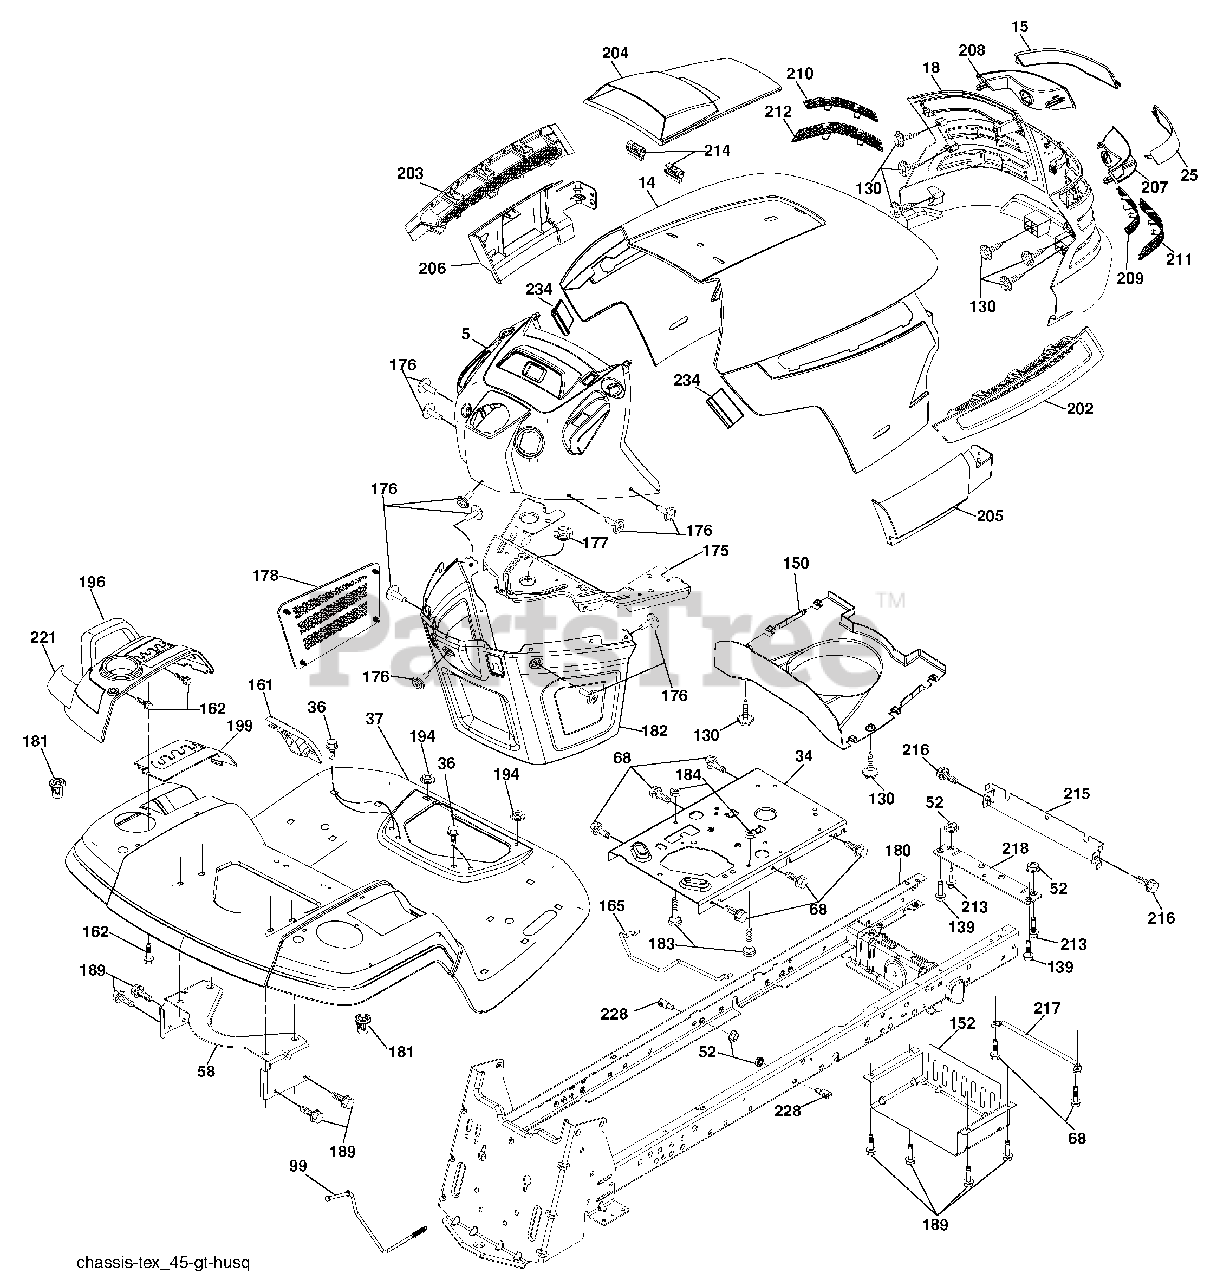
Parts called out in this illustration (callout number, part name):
5	Dash
14	Hood
18	Grille
34	Plate Engine
36	Screw 5/16-18 x 3/4
37	Fender
52	Nut Crown Lock 5/16-18
58	Bracket Fender
68	Screw 5/16-18 x 1/2
99	Rod Bypass Asm.
130	Screw 10 x 3/4 Single Lead Hex
150	Duct Heat Hood
152	Shield Browning/Debris
161	Console Fuel Window
162	Screw Hex Wsh Hi-Lo 1/4 x 1/2
165	Bracket Support Tank
175	Crossmember
176	Screw 10-24 x 5/8 Wshd Qdrx
177	Bushing Steering
178	Cargo Asm. Net
179	Plug N/Cruise
180	Chassis
181	Bushing Mtg. Fender Crgo.
182	Dash Lower
183	Bolt Fin Hex 5/16-18 unc x 1-1/4
184	Spacer Fender
189	Screw 5/16-18 x 3/4
194	Nut Lock Hex Flange 5/16-18
196	Console Asm. Deck Lift
199	Plate Deck Lift
202	Vent Side Hood RH
203	Vent Side Hood LH
204	Vent Asm Hood Top
205	Skirt Hood Side RH
206	Skirt Hood Side LH
209	Insert Hex Top RH
210	Insert Hex Top LH
211	Insert Hex Bottom RH
212	Insert Hex Bottom LH
213	Bolt Hex Hd 5/16-18 unc x 3/4
214	Clip Retainer
215	Cover Chassis Front
216	Screw 5/16-18 x 1/2
217	Rod Pivot
221	Reflector LH
228	Stud Fastner
234	Bumper Hood
